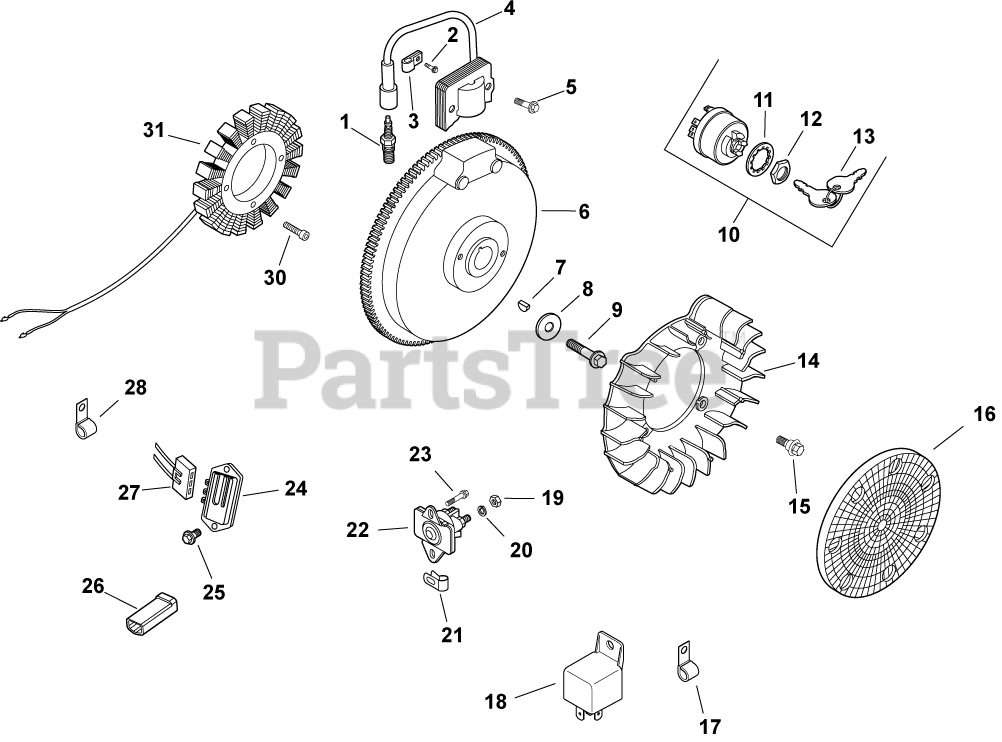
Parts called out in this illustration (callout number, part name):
1	PLUG, SPARK (PRO SERIES)
2	SCREW, FLG THD FRM M5X.8X10
4	MODULE, IGNITION
5	SCREW, FLG THD FRM M5X.8X20-(#25086399S)
6	FLYWHEEL - USE 12 025 72-S
7	KEY, 3/16" X 5/8"
8	WASHER, FLAT 13/32"
9	SCREW, FLG M10X1.5X45 - (#25086361S)
10	SWITCH ASSY, KEY (KM)-USE 25 099 32-S
11	WASHER, INTERNAL TOOTH
12	NUT, KEY SWITCH
13	KEY, SET -USE 48 340 01-S
14	FAN - DISCONTINUED
15	BOLT, SHOULDER
19	NUT, JAM 1/4-20 GRADE 2
20	WASHER, INT TOOTH LOCK 1/4"
21	CLIP, CABLE
22	SOLENOID - WATERPROOF (KM)-USE 25 435 08
23	SCREW,FLG THD FRM M6X1.0X16-(#25086397S)
24	REG/RECT-15 AMP (KM)-USE 41 403 10-S
25	SCREW, FLG M6X1.0X16
26	CONNECTOR (1 CONTACT)
27	CONNECTOR, BODY (KM)-USE 25 155 41-S
28	CLIP, TUBE & WIRING (KM)
29	SCREW, M5X0.8X25 - (#25086402S)
30	KIT, 15 / 20 AMP STATOR
X-6-45-S	SCREW,CAP HD 5/16-24x5/8"
